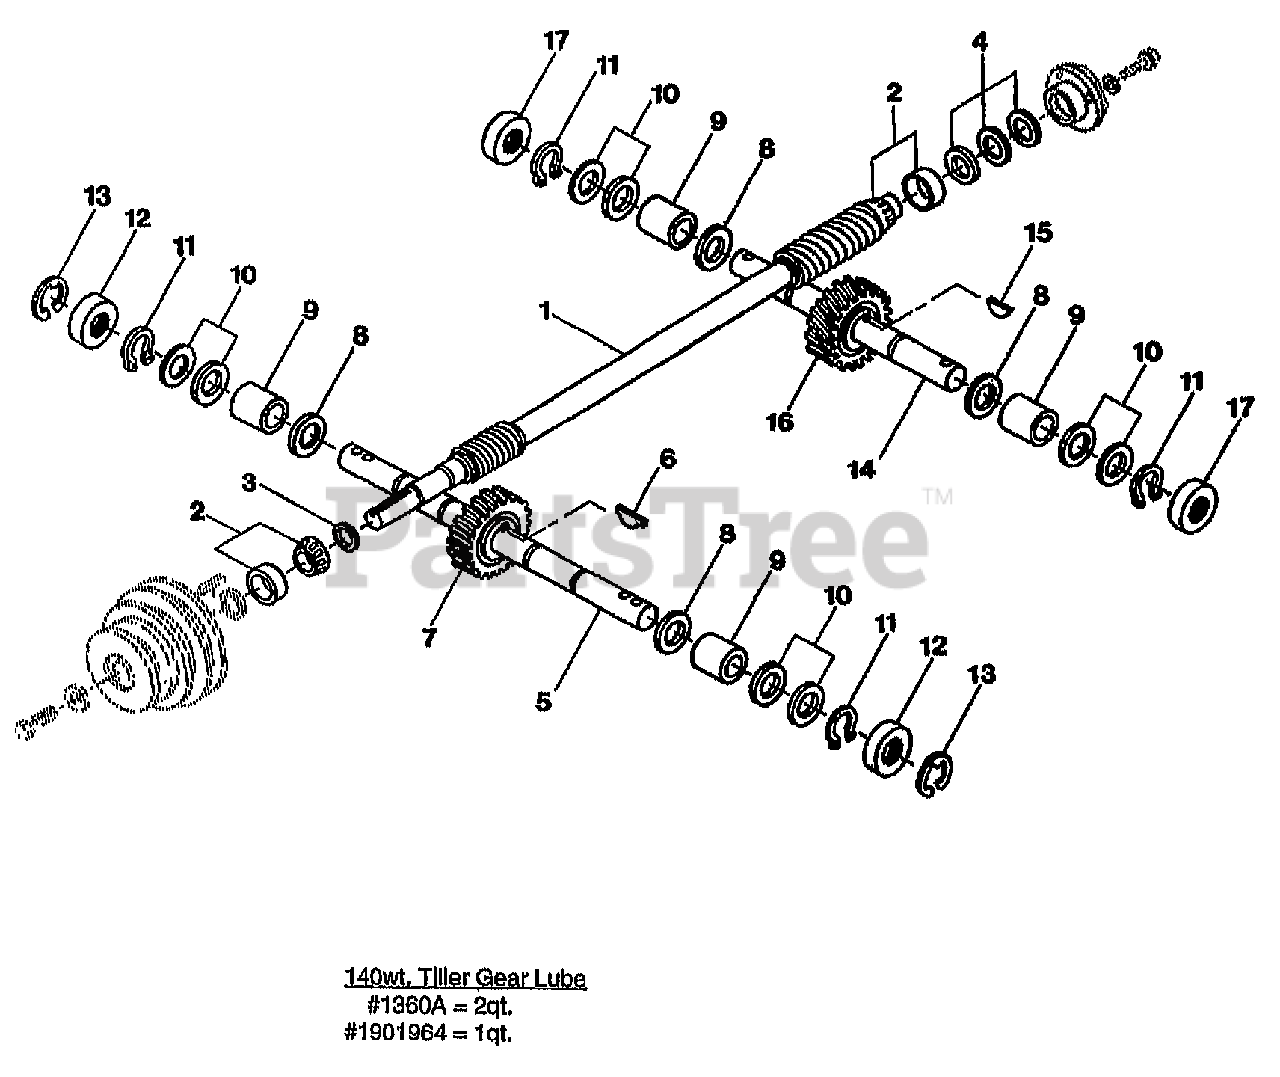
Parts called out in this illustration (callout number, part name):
1	DRIVESHAFT W/BRG-IW (With Rear Bearing Cone pressed on.)
2	KIT-BRG CONE&RACE-DRIVESHAFT
3	WASHER-#1.25X.75X.06 (Drive Shaft)
4	SHIM SET-DRIVESHAFT-HORSE
5	WHEELSHAFT-W/KEY
6	KEY-HI PRO .25X1.062
7	GEAR-WORM 61 TEETH MACH (Wheel Shaft)
8	SHIM-1.234X1.015X.062
9	BUSHING-1.25X1.005X1.5
10	SHIM-1.375X1.015X.062
10	SHIM-1.375X1.015X.03
10	SHIM-1.375X1.015X.015
10	SHIM-1.375X1.015X.01
11	RING-HEAVY EXT .906 ID
12	SEAL-OIL WHEELSHAFT
13	RING-RETAINING 5133-989 (External)
14	TILLERSHAFT-W/KEY
15	KEY-WOODRUFF .25X1.12
16	GEAR-WORM BRONZE MACH
17	SEAL-OIL TRIPLE LIP
